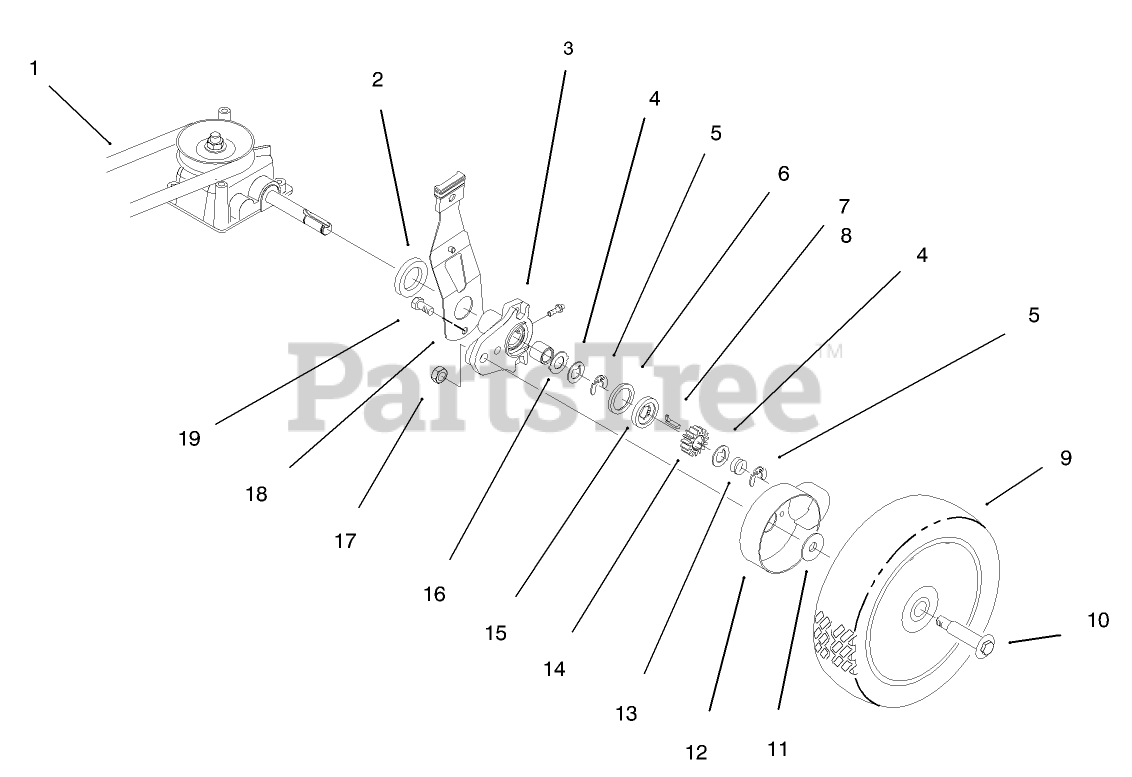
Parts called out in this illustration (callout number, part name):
1	V-BELT
2	SPACER-SHAFT, AXLE
3	REAR HEIGHT ADJUSTMENT ARM ASM
4	WASHER-THRUST, KEYED
5	RING-RETAINING,CLIP
6	RING-FRICTION
7	KEY-ROCKING, RH
8	KEY-ROCKING, LH
9	WHEEL ASM
10	BOLT-SHOULDER
11	WASHER-STEPPED
13	SPRING-COMPRESSION
14	GEAR-PINION
15	WASHER-CLUTCH
16	WASHER-ARM, PIVOT
17	NUT-JAM, LOCKING
18	REAR SPRING ARM ASM
19	SCREW-HWH
